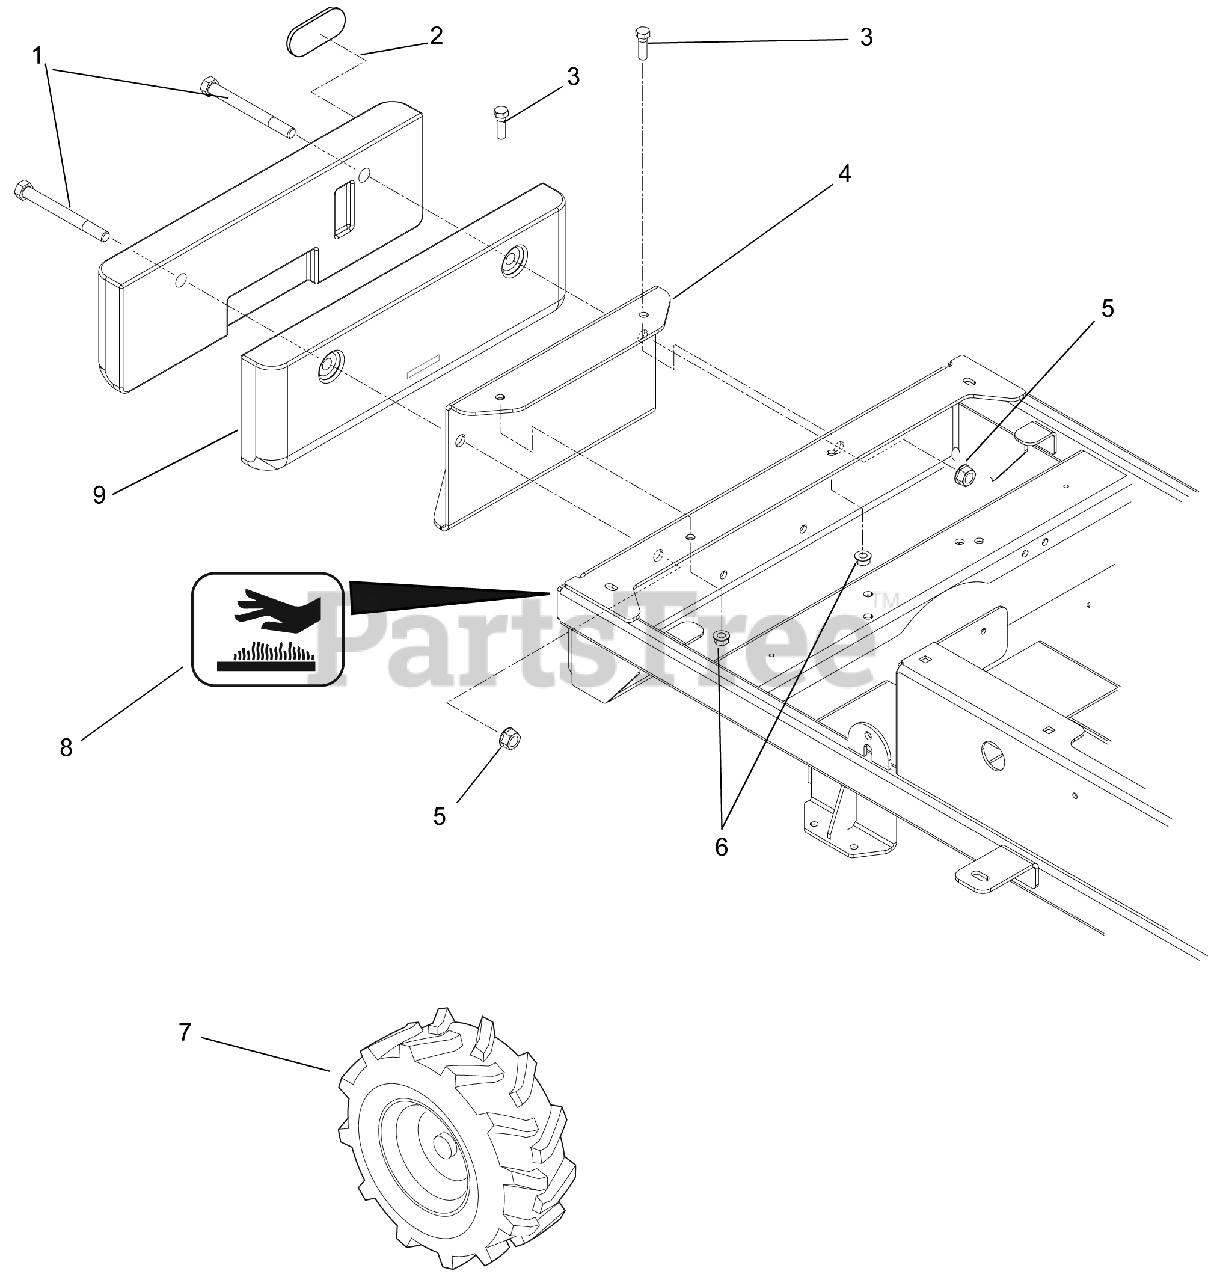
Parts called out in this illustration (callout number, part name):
1	@BLT-HEX .50-13X5.00 GR5 YWZC
2	REFLECTOR,TAIL(AGRI-FAB)
3	@BLT-HEX .38-16X1.25 GR5 YWZC
4	BRKT, WEIGHT
5	@NUT-LK-TOP-FLG .50-13 YWZC
6	@NUT-LK-TOP-FLG .38-16 YWZC
7	ASSY,WHEEL & TIRE 18X6.5 S-HOG
8	DECAL, HOT SURFACE
9	WEIGHT, CAST IRON
